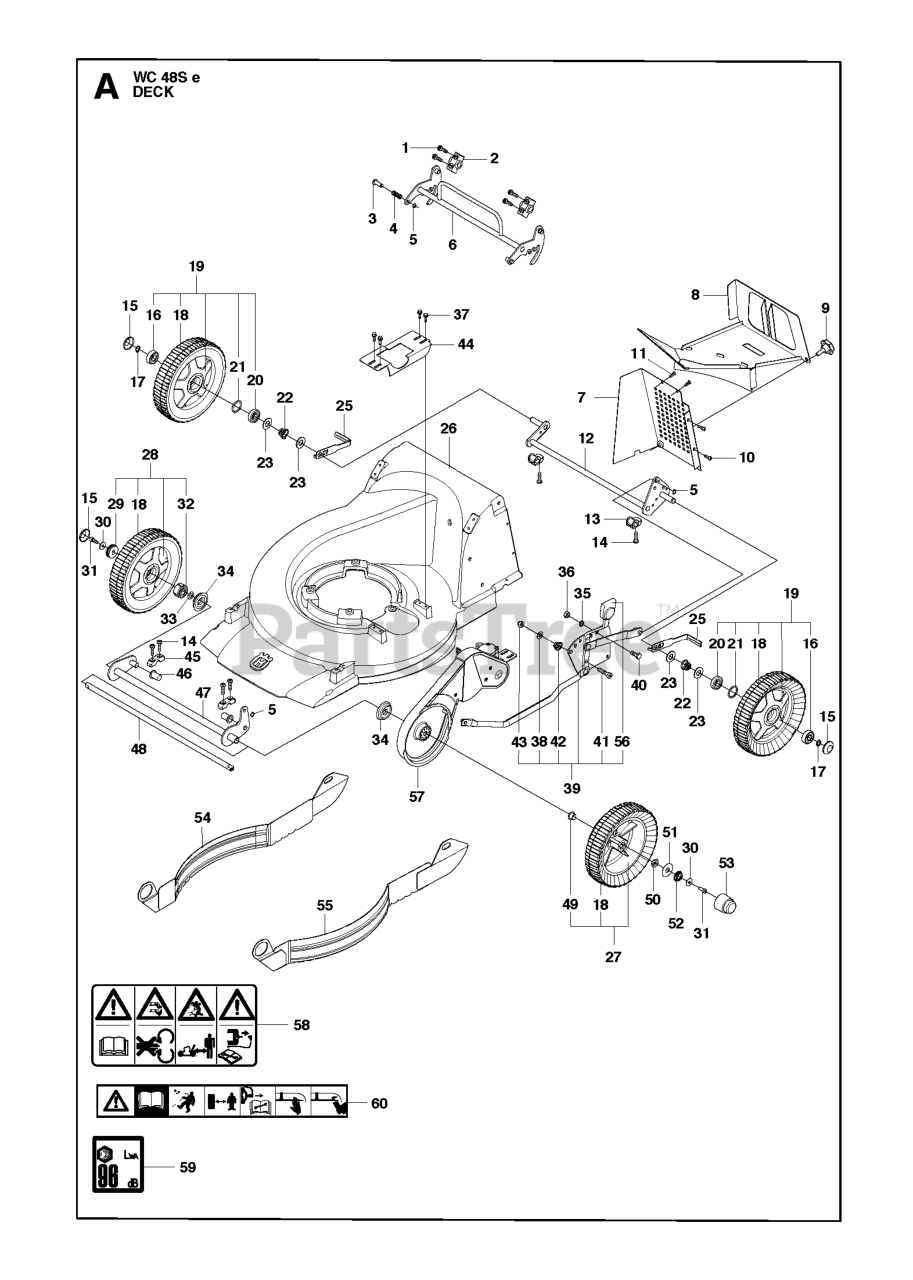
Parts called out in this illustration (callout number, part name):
5	RETAINING RING SGA 8
36	NUT
43	NUT LOCK - M8, NYLOCK
